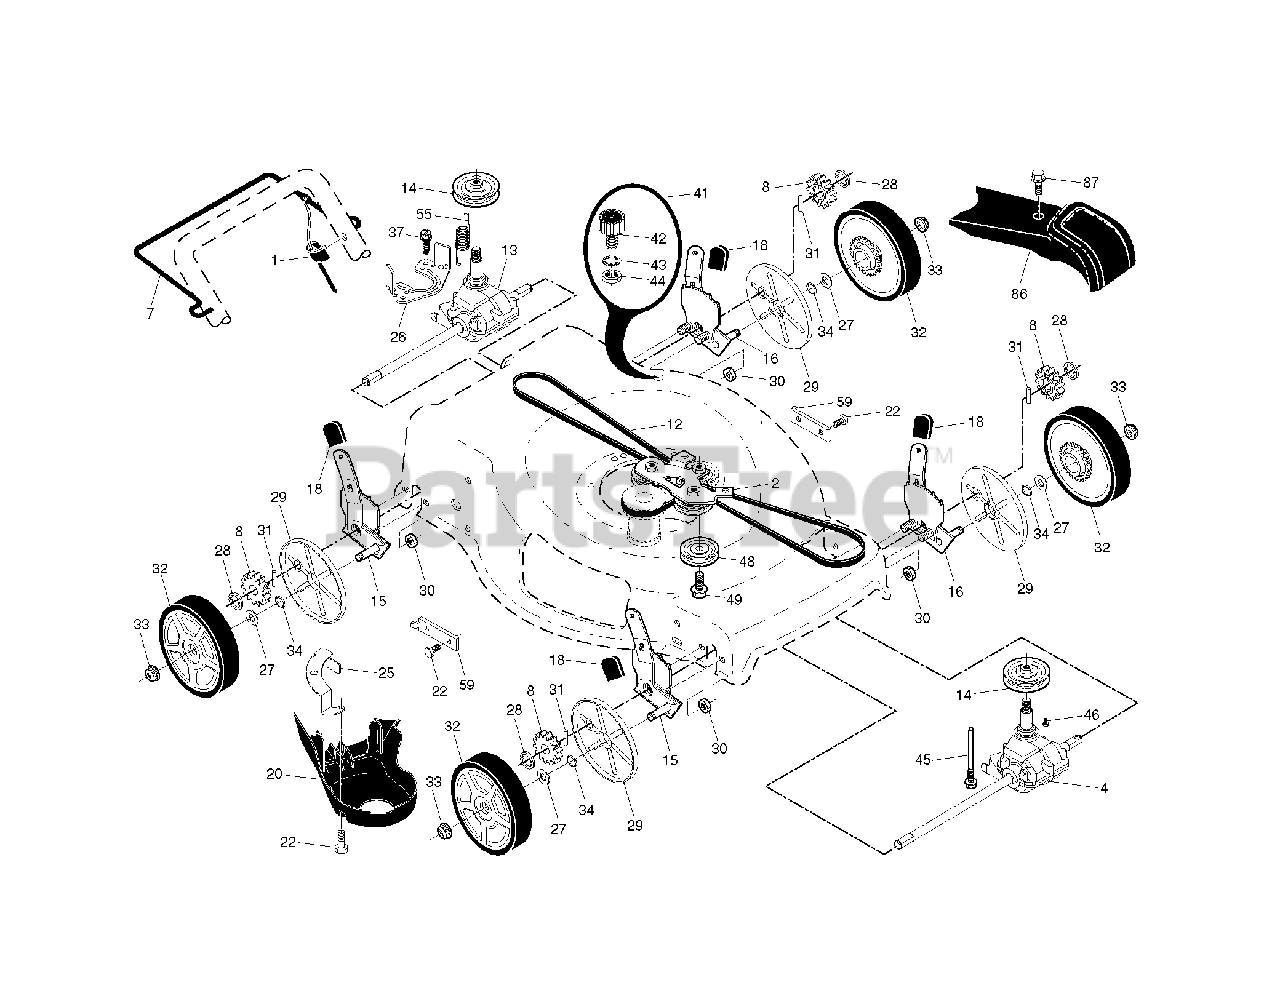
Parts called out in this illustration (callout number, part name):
1	Drive Cable, AWD
2	Bracket Assembly, AWD Bzp Black
4	Transmission, 22+ Awd Frt
7	BAIL.DRIVE.S/S.ROUND.MARI.21
8	PINIION.14.TOOTH.RGD
12	Clutching Cover Belt, 3L 64.10
13	TRANSMISSION.22+AWD.WALK.MOWER
14	Drive Pulley, Sm Awd/Rwd
15	Adjuster Assembly Kit, RH Front
16	Adjuster Assembly Kit, LH Front
18	SELECTOR KNOB
20	COVER.REAR.DRIVE.22+2013
22	BOLT.5/16HEX.WHS.HD
25	BRACKET.DRIVE.COVER.RGD.BZP
26	BRACKET.TRAN.BELTKEEPER.22+RGD
27	WASHER FLUT
28	E-RING 7/16 RE
29	COVER.DUST.WHEEL.INNER.WALK
30	NUT.FLANGE.1-4-20-SERR
31	PAWL, DRIVE
32	WHEEL.8X1.75.5SPK.RAD3.421.BU2
33	NUT.HEX.FLANGE.3/8-16.LOCKNUT
34	O-RING..070X.487.NEOPRENE
41	KIT.WASH-OUT.PORT
42	FITTING, HOSE, WATER WASHOUT
43	WASHER.LOCK.INTERNAL.TOOTH
44	LOCKNUT.HEX.WITH.O-RING
45	Screw, Hi-Lo.5/16-14 X 4.10
46	SCREW.HI-LO. 5/16 X 1.00
48	Idler Pulley Assembly, 22+ AWD
55	SPRING.RETURN.AUTO.
59	BRACKET.SUPPORT.22+RWGD.BZP
86	COVER.DR.22 AWD.GENERIC
87	SCREW, HEX HD TAPPING #10-24 1
